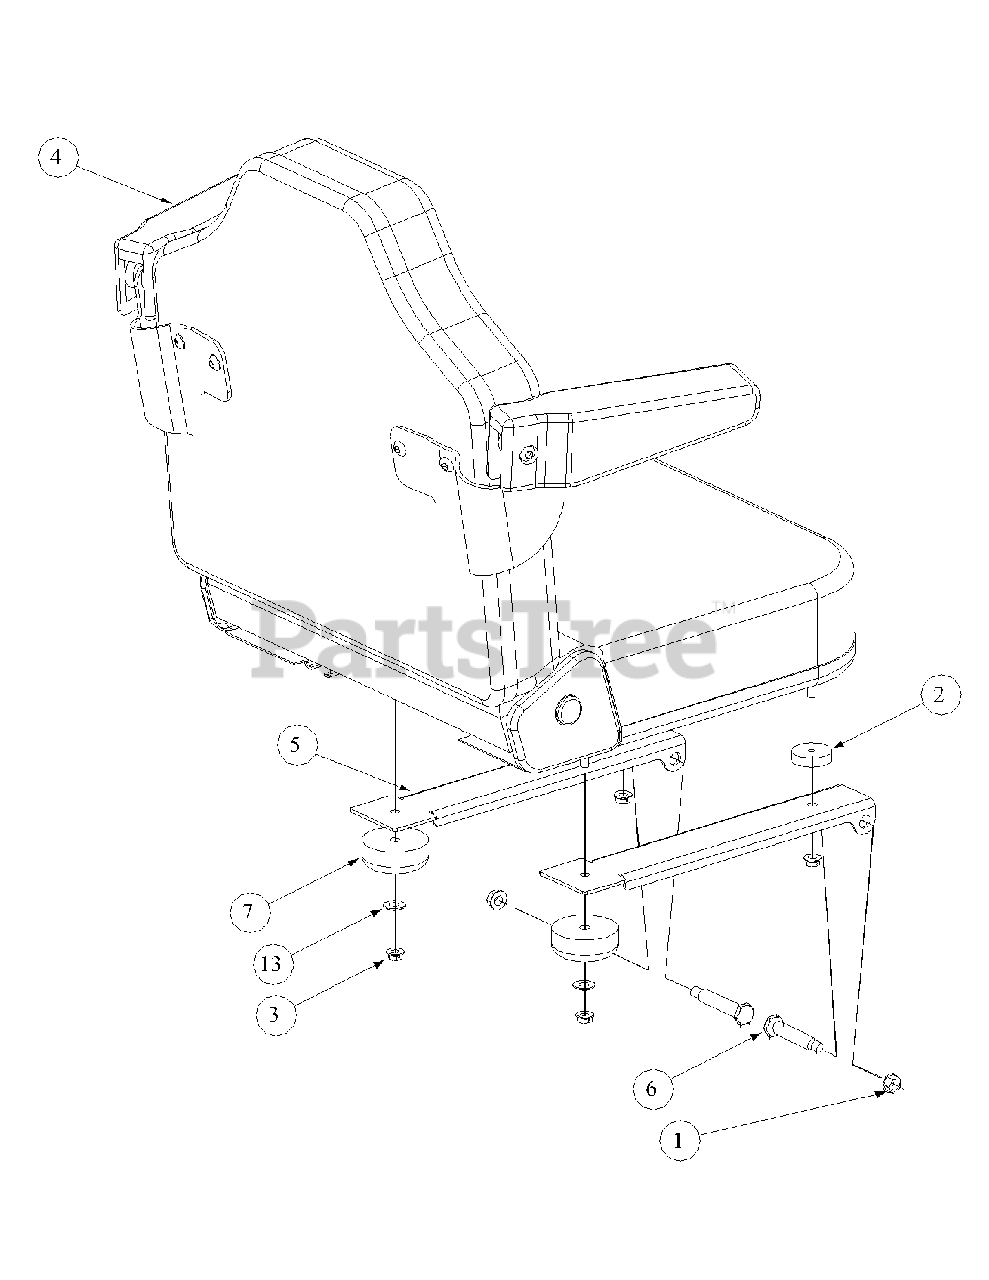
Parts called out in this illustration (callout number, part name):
1	Nut, Hex 3/8-16 Flange Lock
2	Spacer, 0.345 ID x 1.50 OD x .41
3	Lock Nut, Hex Flange, 5/16-18
4	Adjustable Seat, Black embossed, Forward Fold
5	Mounting Bracket, Seat
6	Shoulder Screw, .50x2.345, 3/8-16
7	Grommet, 2.5 OD x 1.0 Long
13	Washer, .325 ID x .930 OD x .045
